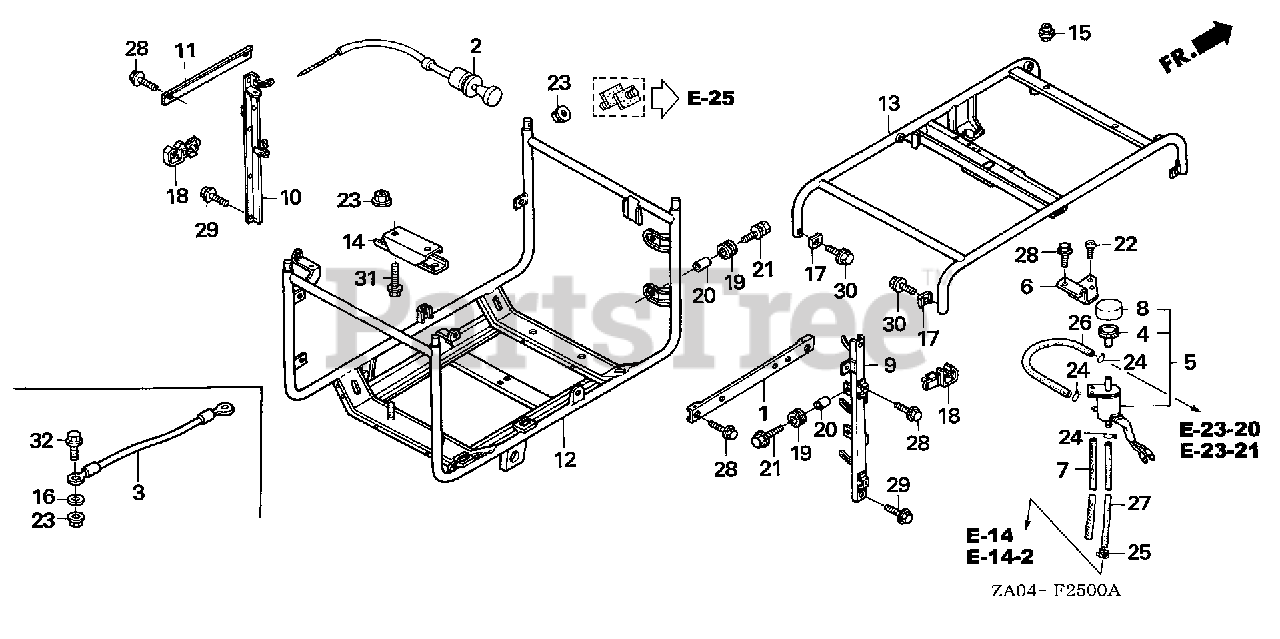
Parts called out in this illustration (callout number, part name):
1	STAY, FR. TANK
2	CABLE, CHOKE
4	FILTER ASSY., SOLENOID VALVE
5	VALVE ASSY., CONTROL
6	STAY, IDLE CONTROL
7	PROTECTOR, TUBE (9X210)
8	CAP, AIR FILTER
9	PILLAR, FR.
10	PILLAR, RR. (NOT AVAILABLE)
11	GUARD, RR.
12	FRAME (LOWER)
13	FRAME (UPPER) (NOT AVAILABLE)
14	RUBBER, GENERATOR MOUNTING
15	CUSHION, TOP COVER
17	WASHER, FRAME JOINT
19	RUBBER, CONTROL BOX
20	COLLAR, CONTROL BOX
21	BOLT-WASHER (6X20)
22	SCREW, PAN (5X8)
23	NUT, FLANGE (10MM)
24	CLIP, TUBE (B7)
25	CLAMP, TUBE (D8)
26	BULK HOSE, VACUUM (3.5X1000) (3.5X170)
27	BULK HOSE, VACUUM (3.5X1000) (3.5X230)
28	BOLT, FLANGE (6X12)
29	BOLT, FLANGE (8X12)
30	BOLT, FLANGE (8X16)
31	BOLT, FLANGE (10X25)
